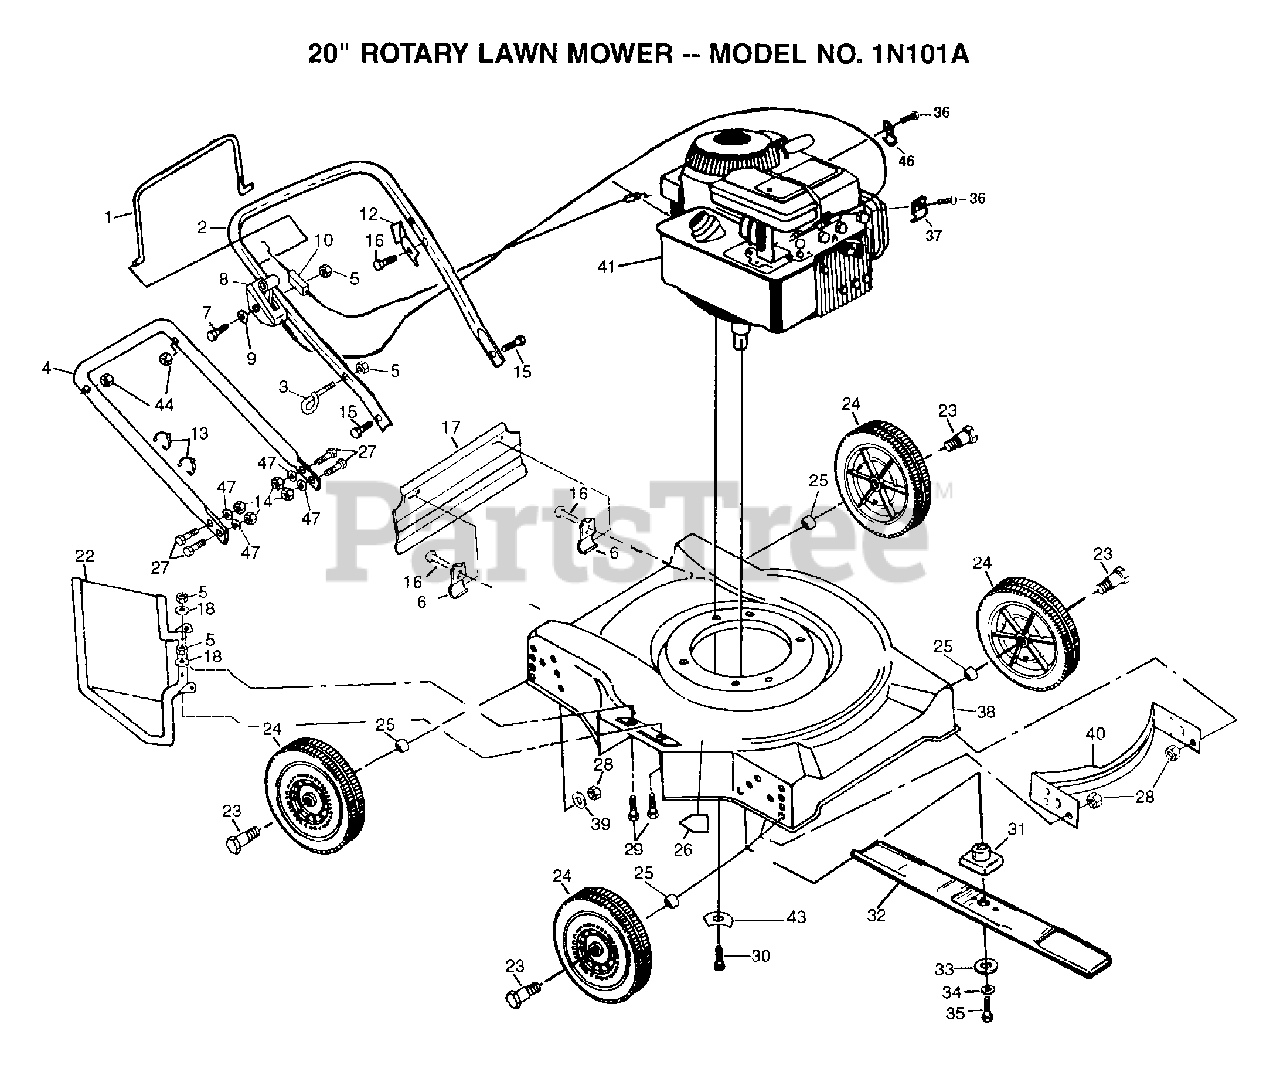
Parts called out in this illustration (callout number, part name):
1	CONTROL BAR PM
2	UPPER HANDLE
3	ROPE GUIDE
4	HANDLE LWR PM
6	"BRKT,DEFL PM"
9	WASHER PM
10	CABLE.CONT.ENG
12	"BRKT,UPSTOP"
14	LOCKNUT
15	BOLT LT
16	TAPPING SCREW
22	"GRD,DISCHARGE"
23	AXLE BOLT
24	WHEEL ASSY
26	DECAL HYT
28	LOCKNUT PM
29	BOLT 1/4-20-1 1/2
30	SCREW
31	BLADE ADAPTOR
32	BLADE.STAND.20INC
33	"WASHER,HARDEN"
34	LOCKWASHER
35	SCREW
36	SCREW PM
37	CABLE CLAMP
46	GUIDE CLIP PM
47	STEEL WASHER
